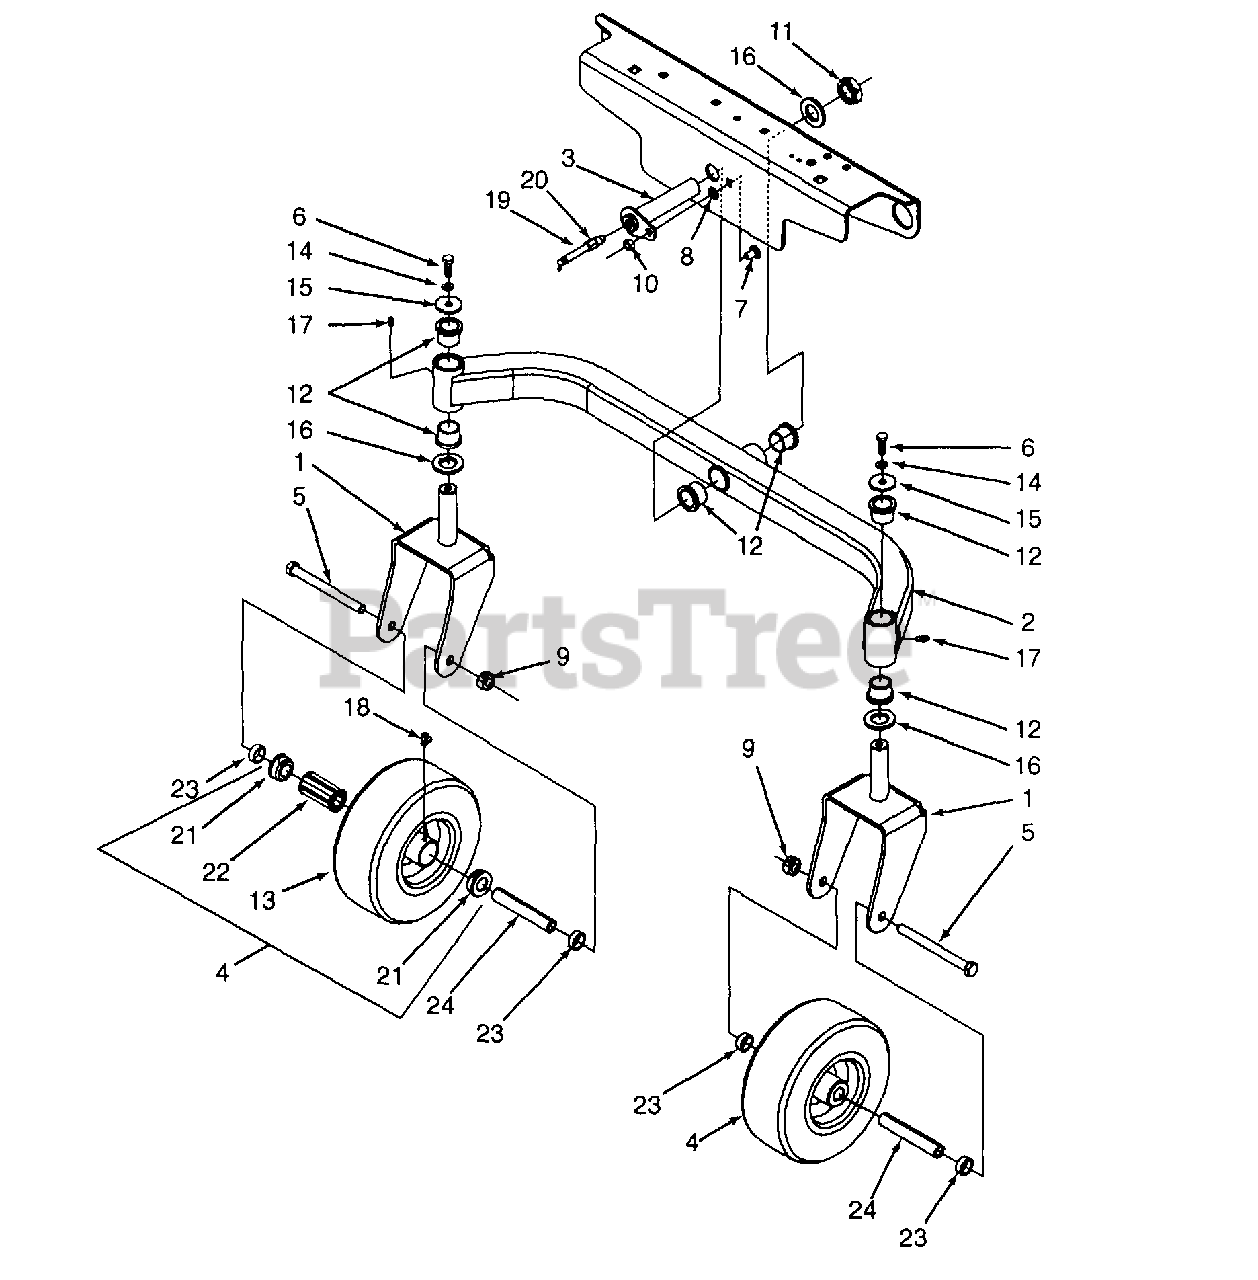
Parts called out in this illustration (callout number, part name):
4	Wheel Comp 11.0 x 4.0 x 5.0
5	Screw, Hex Cap, 1/2-20 x 5.5
6	Screw, Hex Cap, 3/8-16 x 1.0 GR5
7	Bolt, Carriage, 3/8-16 x .75
8	Push Nut, Retainer, 3/8 ID
9	Nut, Hex Center Lock, 1/2-20
10	Nut, Hex Flange Lock, 3/8-16
11	Nut, Hex Lock, 1.0-14
12	Bearing, Flange, 1.0 ID
13	Tire, Urethane, Only
14	Washer, Lock 3/8
15	Washer, Flat, .39 x 1.5 x .134
16	Washer, Special Flat
17	Fitting, Grease
18	Fitting, Grease, 90° Tap 1/4-28
19	Fitting, Grease, 65° w/Extension
20	Adapter, 1/8 NPTF x 1/8 NPTF
21	Bearing, Flange
22	Bearing, Roller
23	Spacer, .79 ID x .347 Lg
24	Spacer, Wheel
